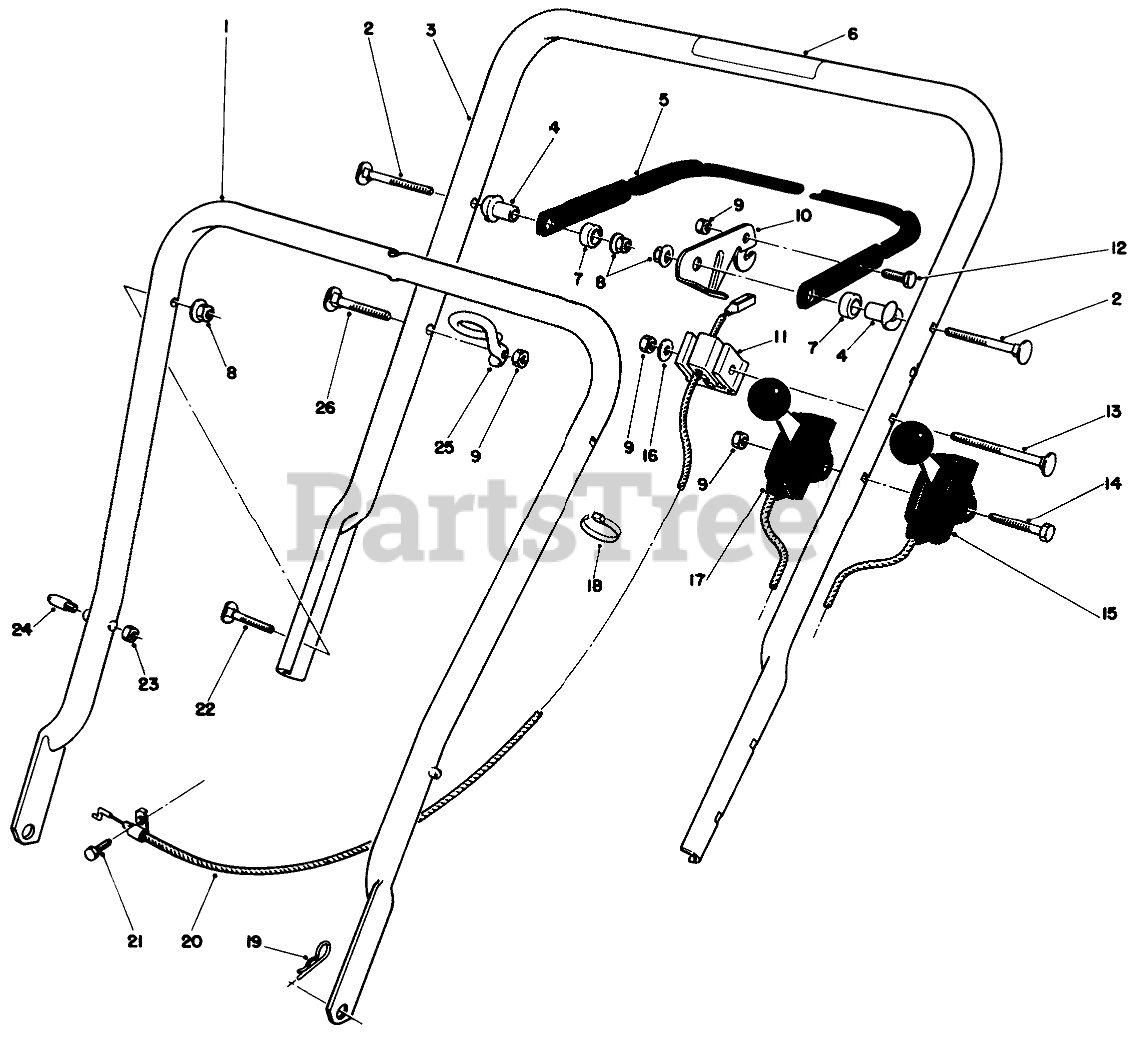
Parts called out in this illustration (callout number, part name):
1	LOWER HANDLE ASM
2	5/16-18 X 2 HNDLE SCREW
3	Handle-Upper (Incl. Ref. #6)
4	SPACER-SUPPORT
5	Bar-Control
6	DECAL - HANDLE
7	SPACER-NYLON
8	NUT-LOCK, NI
9	NUT-LOCK, NI
10	CONTROL LEVER
11	SUPPORT-CABLE
12	SCREW-HH
13	HANDLE SCREW
14	SCREW-HH
15	TRACTION CONTROL
16	WASHER-FLAT
17	THROTTLE CONTROL
18	TIE-CABLE
19	PIN-COTTER, HAIR
20	BRAKE CABLE
21	SCREW-HH
22	SCREW
23	NUT-LOCK, NI
24	HANDLE PIN
25	Guide
26	HANDLE SCREW
